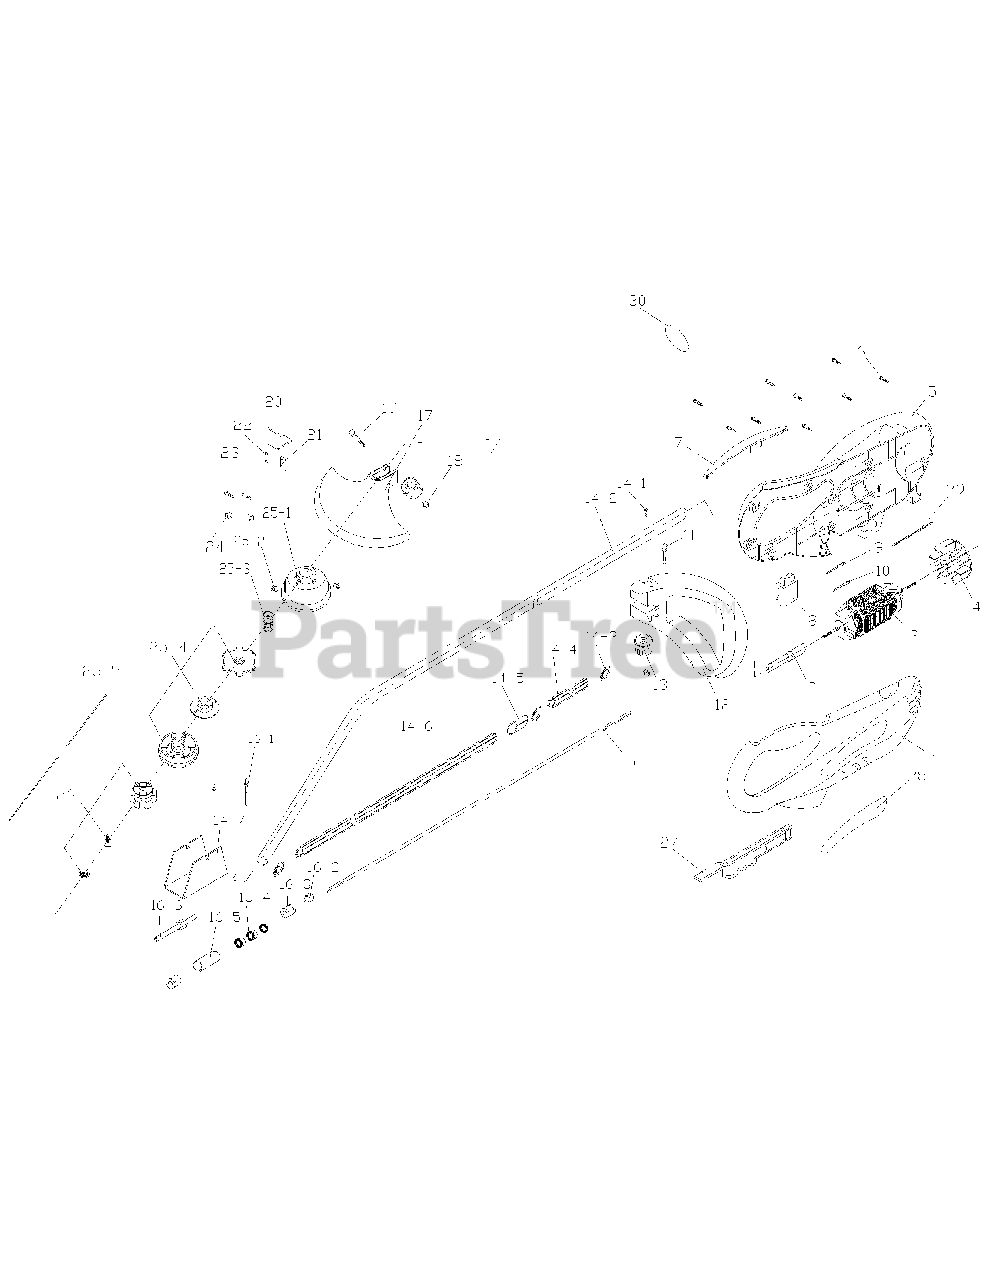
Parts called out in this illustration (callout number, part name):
1	HOUSING (L)
2	CONNECTING HEAD ASS'Y
5	HOUSING (R)
7	READ HOUSING
12	ASSIST HANDLE
14	SHAFT ASS'Y
15	FLEXIBLE SHAFT
16	CONNECTING HEAD ASS'Y
20	SUPPORTING BAR
25	CUTTING LINE ASS'Y
26	KNOB ASS'Y
